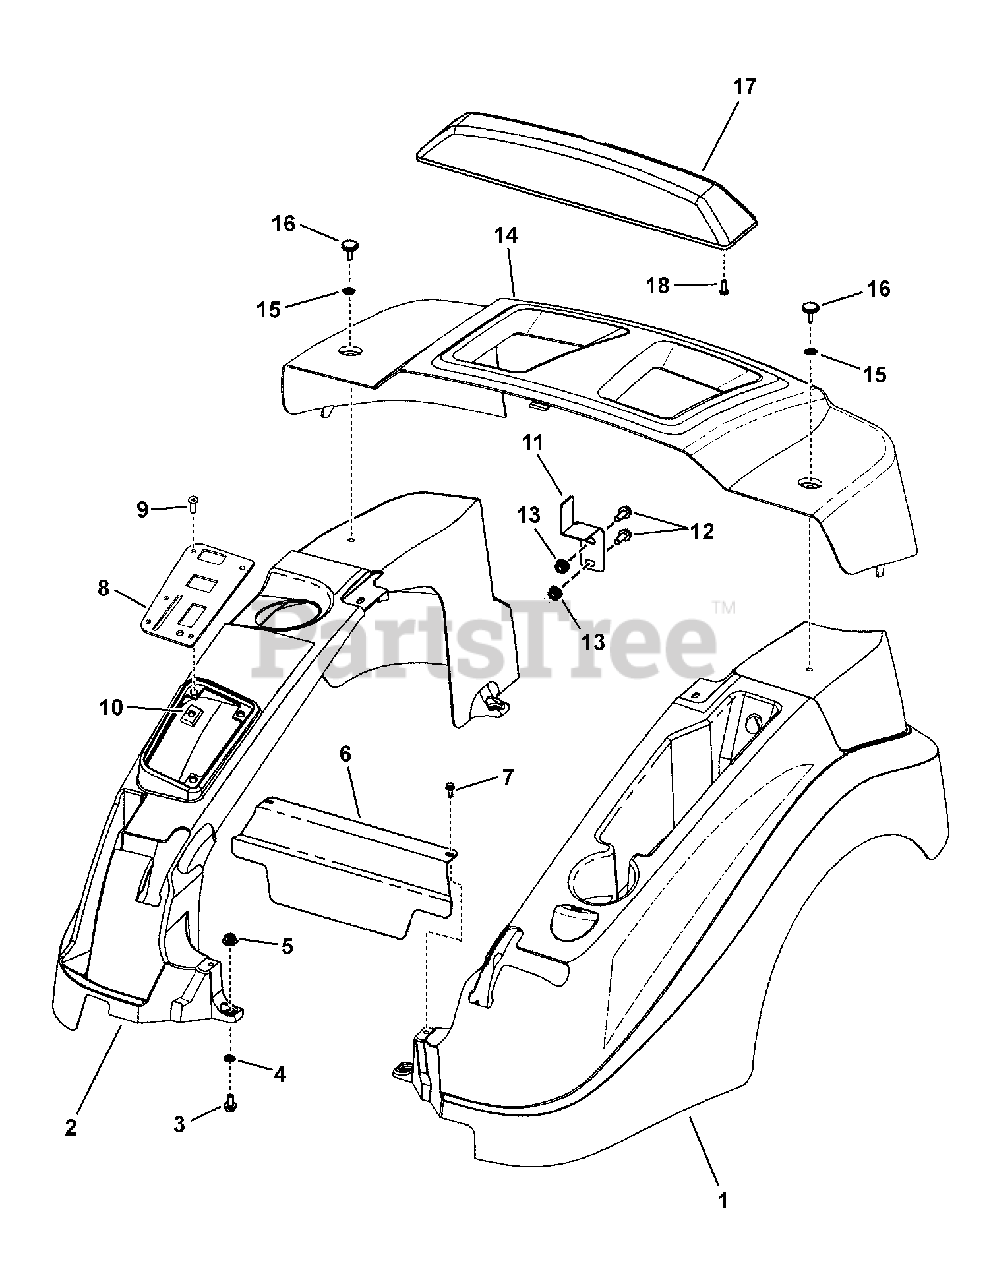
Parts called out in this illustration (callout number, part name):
1	FENDER, LH RZT
2	FENDER, RH RZT
3	BOLT, 5/16-18 x 5/8" Hex Flange Lock, GR 5
4	BOLT RETAINER, 5/16" Black
5	NUT, 5/16-18 Hex Large Flange Center Lock
6	COVER, Front, Snapper
7	SCREW, 1/4-20 x 5/8" Hex Washer Self-Tap, YZ
8	PANEL, Control
9	SCREW, 1/4-20 x 5/8" Pan Head Self-Tap (Torx)
10	U-NUT 1/4-20
11	BRACKET, RH Fender Support (Cardinal Red)
12	BOLT, 5/16-18 x 7/8" Hex Flange Lock, YZ
13	NUT, 5/16-18 Hex Flange Lock, GR 5
14	COVER, Engine, Double Vent
15	WASHER, 1/4" Internal/External Tooth Lock
16	3-PRONG KNOB, 1/4-20 x 1/2"
17	GUARD, Rear Seat
18	SCREW, 1/4-15 x 1-1/4" Hex Washer Self-Tap
